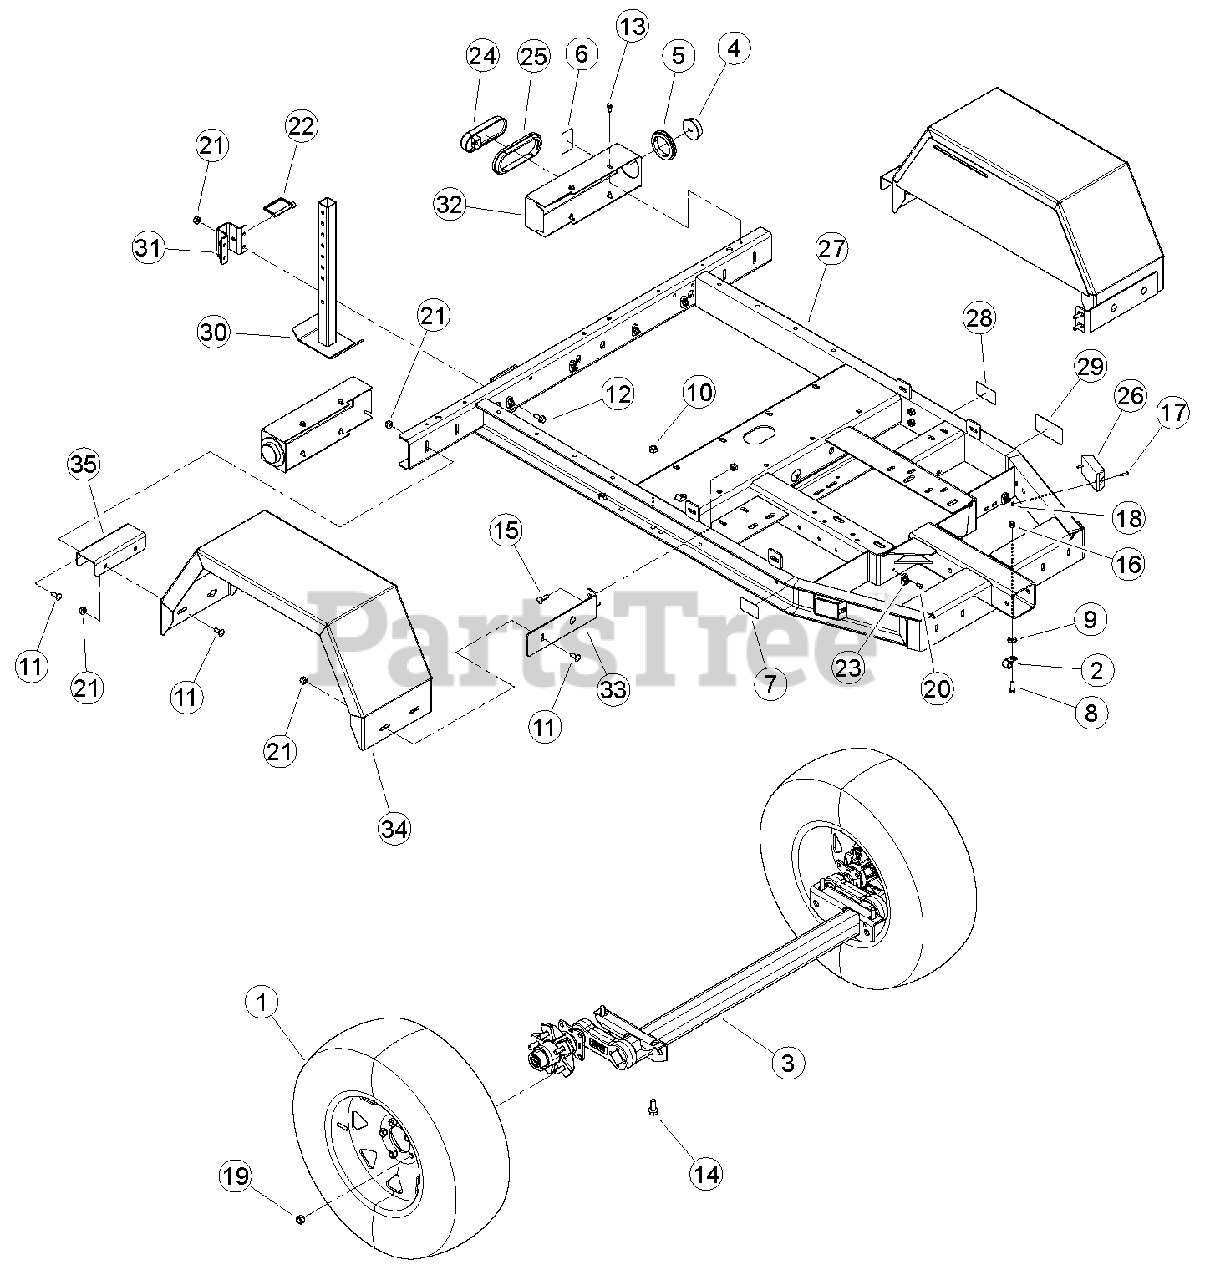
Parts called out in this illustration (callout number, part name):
1	ASSEMBLY, 15 INCH TIRE + WHEEL
2	CLAMP, 9/16 COATED
3	AXLE, 2500 LB TORSION
4	LIGHT, RED CLEARANCE
5	GROMMET, CLEARANCE LIGHT
6	REFLECTOR, WIDE ANGLE RED
7	REFLECTOR, WIDE ANGLE AMBER
8	BOLT, 3/8 X 1 HEX HD GR5 ZP
9	WASHER, 3/8" FLAT ZP
10	NUT, 1/2" CENTERLOCK GRB ZP
11	BOLT, 3/8 X 1" GR5 CRG NC ZP
12	BOLT, 3/8 X 1 FLANGE NC
13	SCREW, 11/32 X 7/8 HWH AB THREAD ZP
14	BOLT, 1/2 -13 X 1-1/4 FLANGE NC
15	BOLT, 3/8 X 1-1/4" GR5 CRG NC ZP
16	NUT, 3/8" NE NYLOCK ZP
17	SCREW, MCH 10-24 X 1" RND HD PHL ZP
18	NUT, 10/24 NYLOCK TYPE NM ZP
19	NUT, 1/2-20 WHEEL
20	RIVET, AL BLIND 1/4 X 3/4 DOME HEAD
21	NUT, 3/8-16 NYLOCK FLANGE
22	PIN, 3/8 X 2-3/4" SNAP
23	CLAMP, CABLE MOUNT
24	TAIL LIGHT, OVAL LED
25	GROMMET, OVAL TAIL LIGHT
26	LIGHT, AMBER MARKER
27	ASSEMBLY, CH611DH TRAILER/DECALS
28	DECAL, P215/70R15 100 LB LOAD RATING
29	DECAL, EPA EMISSION
30	WELDMENT, REAR STABILIZER
31	GUIDE, TRAILER SUPPORT
32	BRACKET, TAILLIGHT
33	BRACKET, FENDER
34	WELDMENT, CHIPPER FENDER
35	PLATE, FENDER SPACER
